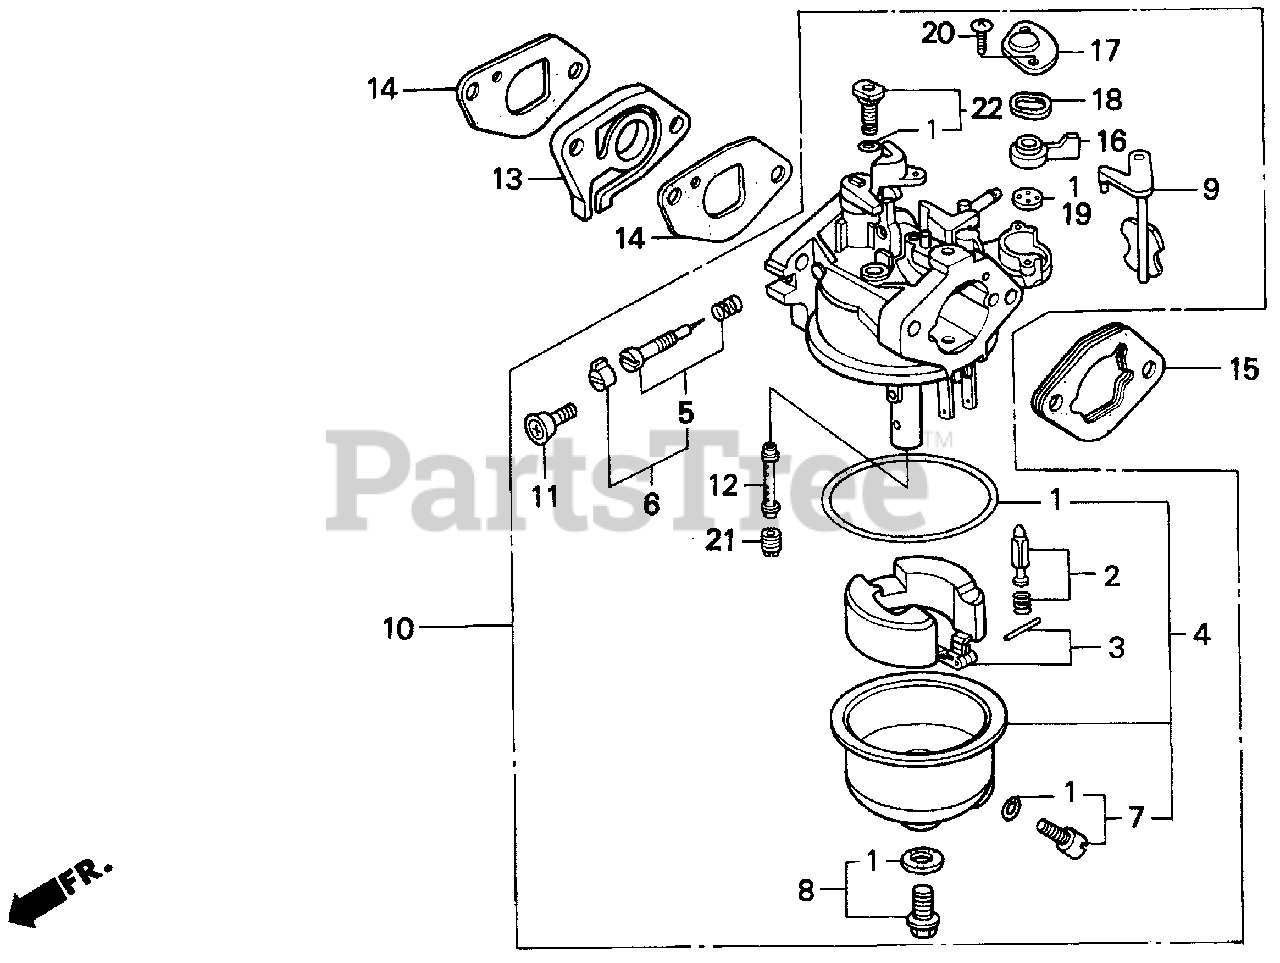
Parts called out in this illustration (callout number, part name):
1	GASKET SET
2	VALVE SET, FLOAT
3	FLOAT SET
4	CHAMBER SET, FLOAT
6	SCREW SET
7	SCREW SET, DRAIN
8	SCREW SET B
9	CHOKE SET
10	CARBURETOR ASSY. (BE56A A)
11	SCREW, THROTTLE STOP
12	NOZZLE, MAIN
13	INSULATOR, CARBURETOR
14	GASKET, INSULATOR
15	SPACER, CARBURETOR
16	LEVER, VALVE
17	PLATE, LEVER SETTING
18	SPRING, VALVE LEVER
19	GASKET, VALVE
20	SCREW, PAN (3X6)
20	SCREW, PAN (3X8)
21	JET, MAIN (#52)
21	JET, MAIN (#55)
21	JET, MAIN (#58)
22	JET SET, PILOT (#38)
